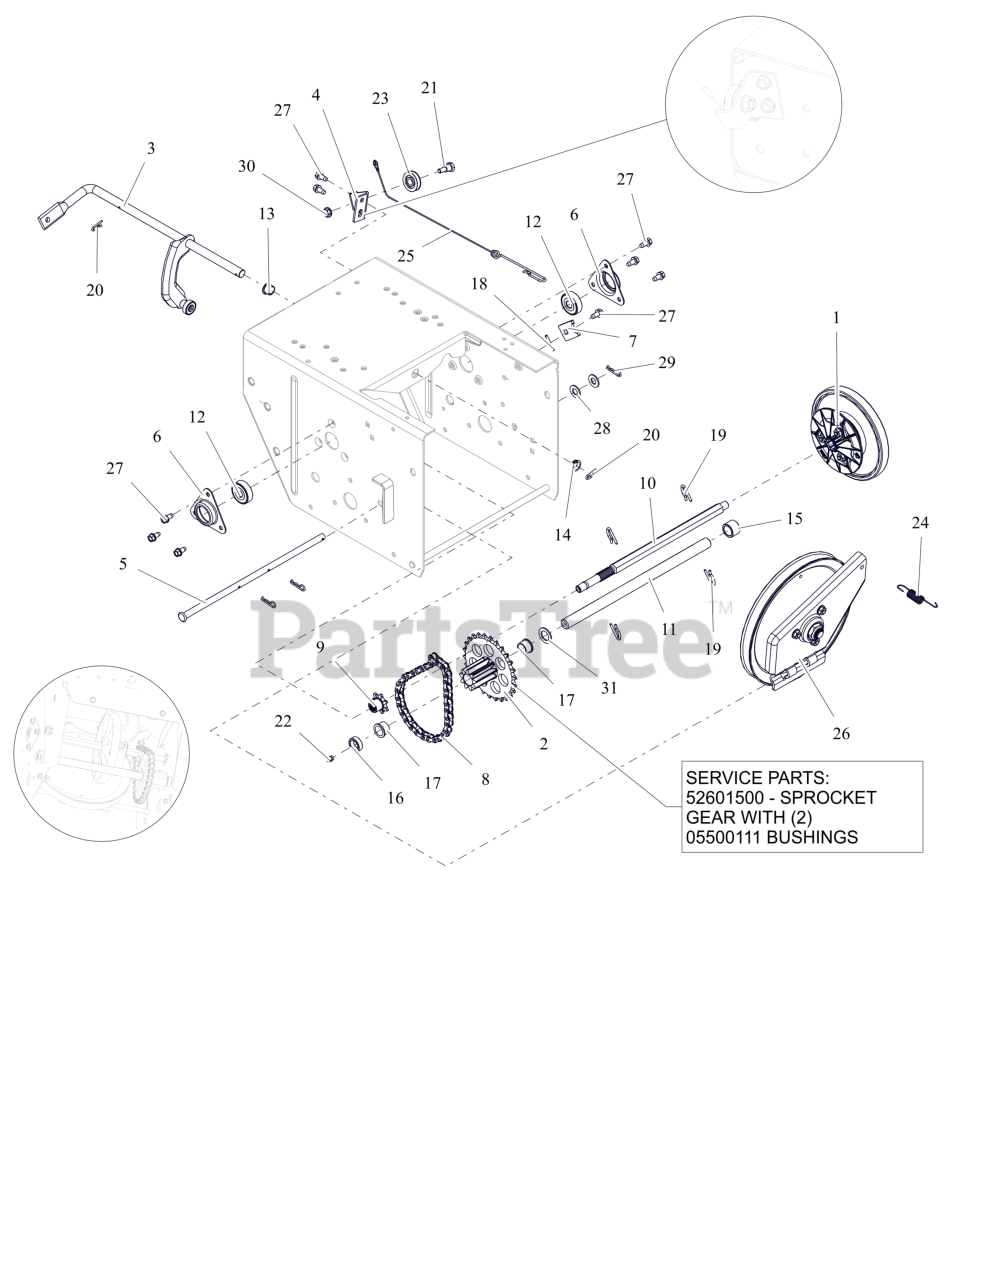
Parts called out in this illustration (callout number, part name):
1	DISC, FRICTION DRIVE-ASSEMBLY
2	PINION & SPROCKET
2	PINION & SPROCKET W/BUSHINGS
3	ARM, SHIFT-PRO (ASSEMBLY)
4	BRACKET, CABLE PULLEY
5	PIN, PIVOT
6	FLANGE, BEARING
7	TAB, ANTI ROTATION
8	CHAIN - #41, 32 PITCHES
9	SPROCKET, PINION 7T W/SPLINE
10	SHAFT, HEX - HEAT TREATED
11	SHAFT, PINION - HARDENED
12	BRG-BALL .437X1.375X.437
13	BUSHING, POLYLINER-.50 SPLIT
14	BUSHING, POLYLINER-.50 SNAPIN
15	SPACER, .635X.880X.611
16	BSHG-SLV, .635X.880X.305
17	BSHG-FLG .625X.750X.500X.875
18	PIN-ROLL .125X1.00
19	PIN, SPRING CLIP
20	CLIP, SPRING
21	BOLT, SHLDR -.375 X .375 X .25-20
22	ZERK,FITTING .25X.125 DRIVE IN
23	PULLEY, CABLE
24	SG-TENS .048X.50X2.8
25	CABLE, LOWER TRACTION,SS & PRO
26	PLATE, SWING ASSEMBLY-DEEP
27	SCR-TAP .25-20X.50 HWH ZCC
28	WSHR,FLT .406X.812X.065 ZCC
29	PIN, HAIR #213 .08X1.19 ZCC
30	NUT-LK-TOP-FLG .250-20 GF ZCC
31	WSHR, FLT .630X1.005X.062 ZCC
